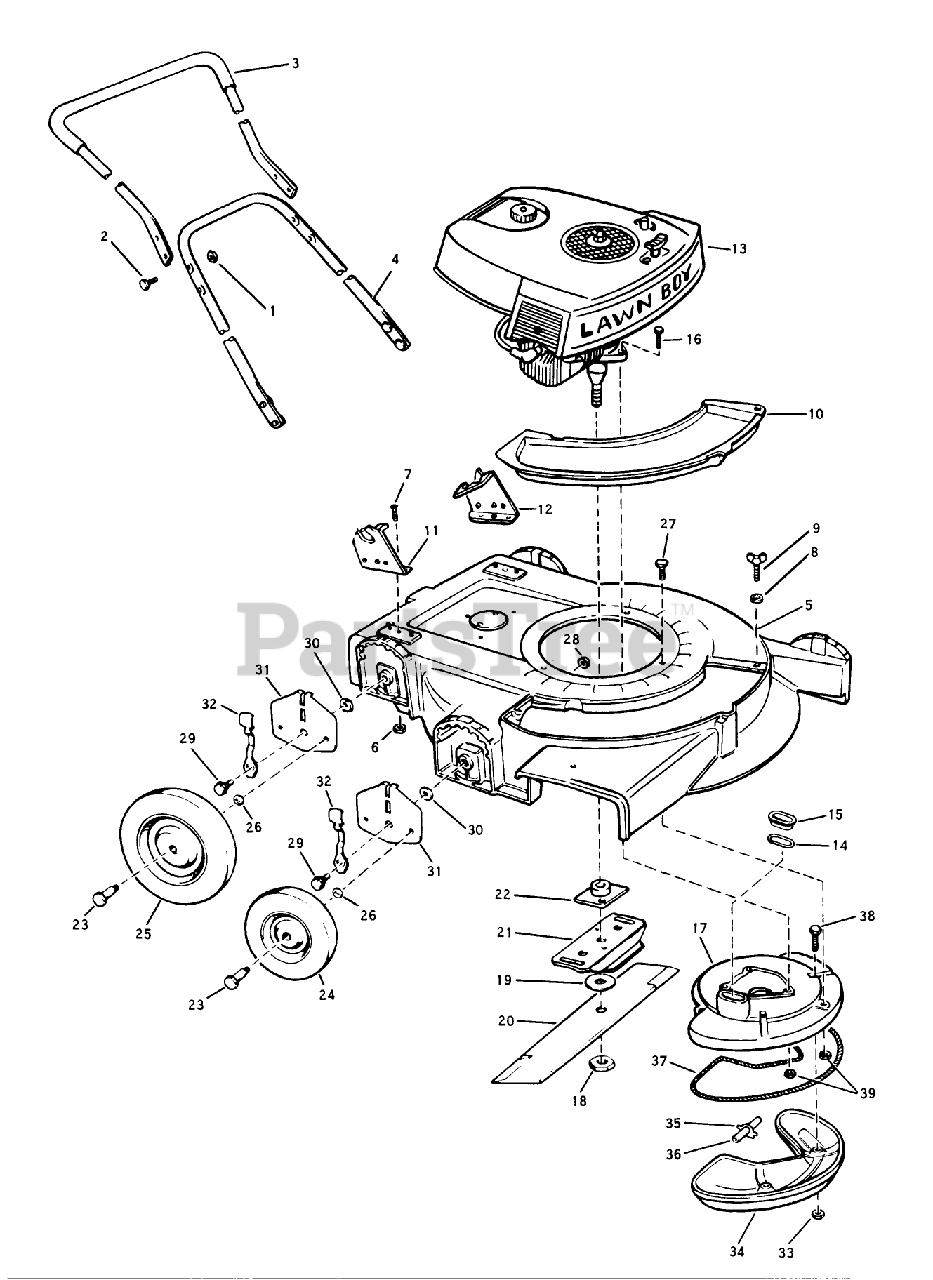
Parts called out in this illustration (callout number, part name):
1	STOP NUT
3	Handle Grip Assy. Top
5	Housing Cover Assy. 21"
7	SCREW S
14	Gasket-Exhaust
18	NUT-BLADE
22	PLATE AND COLLAR ASM
23	BOLT WHEEL
26	WASHER WROUGHT
33	LOCKNUT E
35	Gasket-Internal Tube
36	Tube-Internal Muffler
